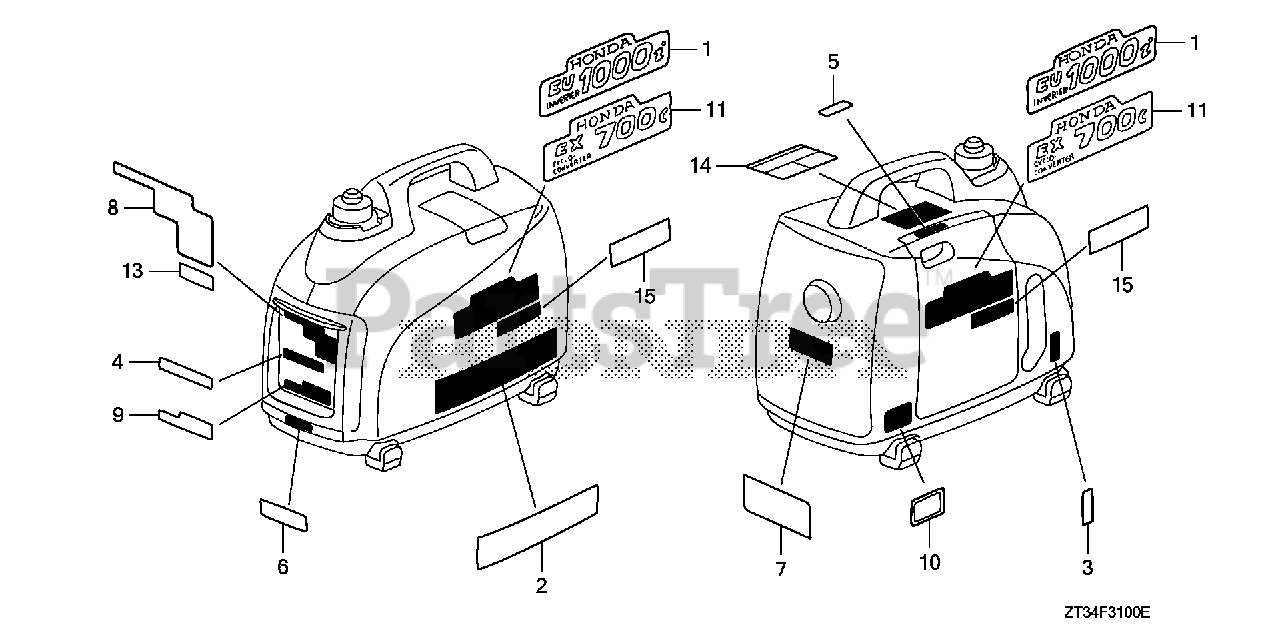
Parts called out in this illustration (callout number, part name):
2	MARK, CAUTION
3	MARK, ENGINE SWITCH
4	MARK, D.C. CAUTION
5	MARK, CHOKE
6	MARK, HONDA
7	MARK, EX. CAUTION
9	MARK, CIRCUIT PROTECTOR
10	MARK, OIL CAUTION
13	MARK, A.C. CAUTION
